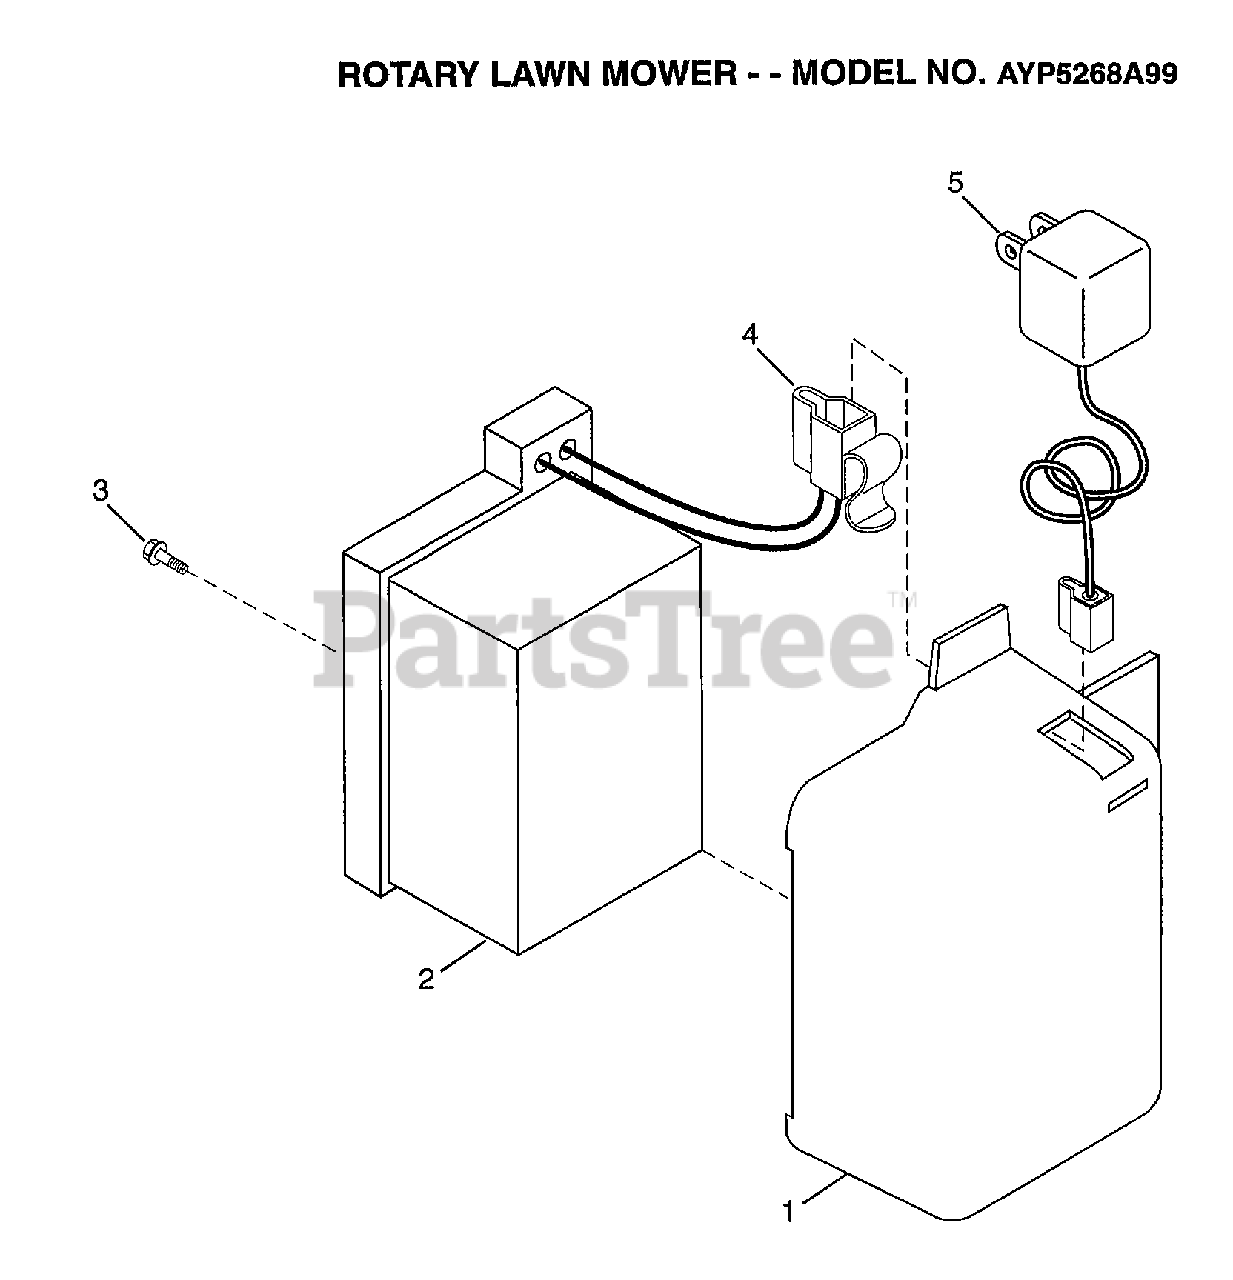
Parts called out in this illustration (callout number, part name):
1	BRKT.BATTERY
3	SCREW.HX.13X.750
4	CONNECTOR PM
5	CHARGER PM
